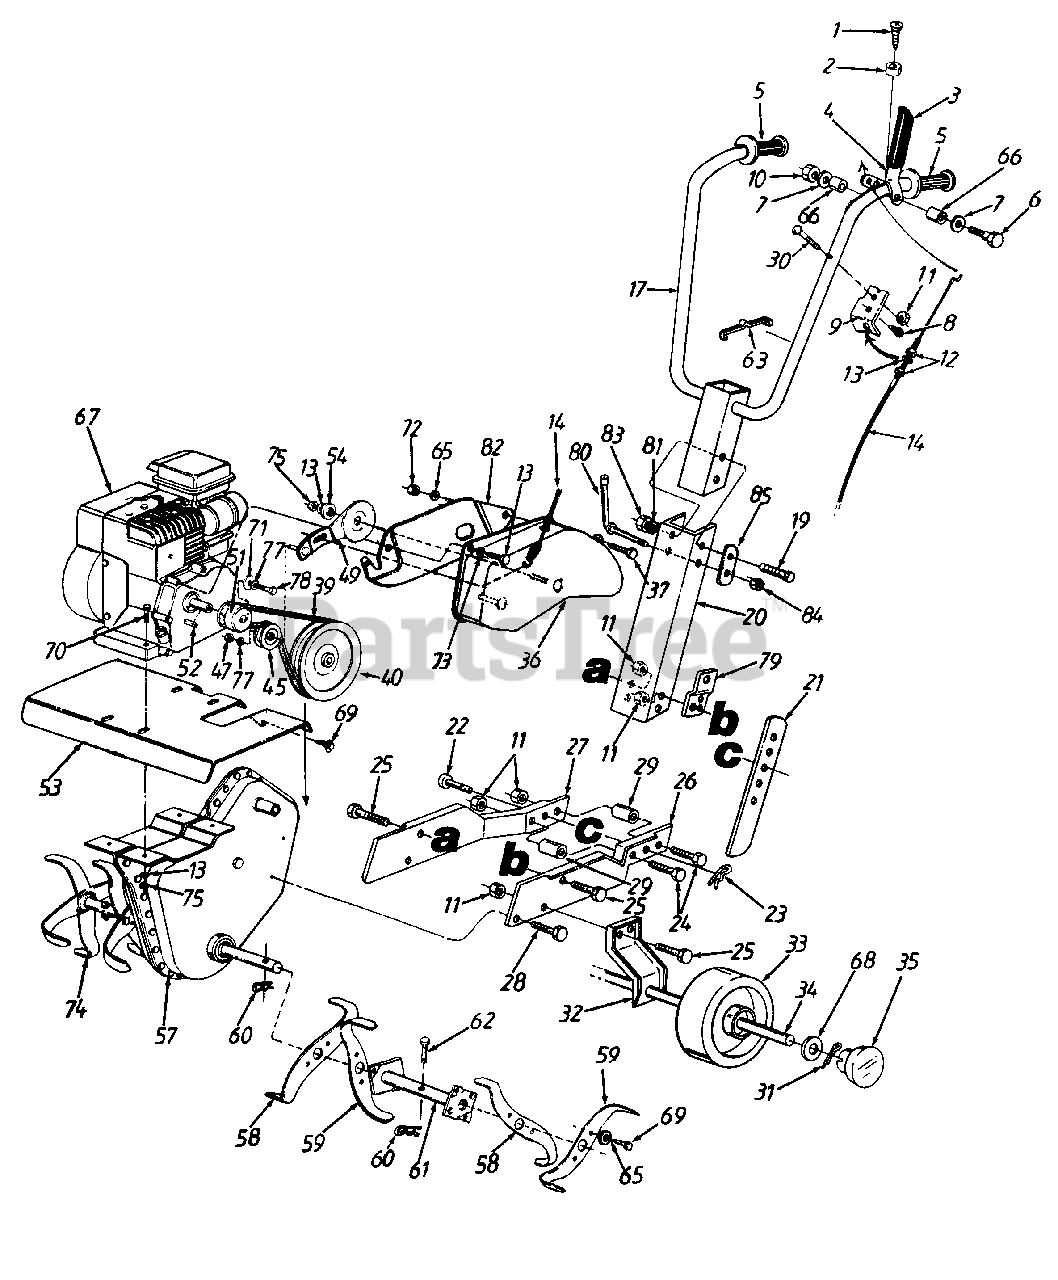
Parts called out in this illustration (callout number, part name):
1	Tap Scr. #10-16 x 1/2" Lg.
2	Rubber Bumper
3	Vinyl Grip
5	Handle Grip
6	Hex Bolt 1/4-20 x 2" Lg.
7	Fl-Wash. 1/4" I.D.
8	Hex Tap Scr. 1/4-20 x 1/2" Lg.
9	Cable Bracket
10	Lock Nut 1/4-20 Thd.
11	Lock Nut 5/16-18 Thd.
12	Hex Jam Nut 5/16-24 Thd.
13	L-Wash. 5/16" I.D.
14	Clutch Control Cable
23	Hairpin Cotter
24	Hex Bolt 5/16-18 x 1" Lg.
25	Hex Bolt 5/16-18 x 5/8" Lg.
29	Spacer
30	Hex Bolt 5/16-18 x 1-1/4" Lg.
31	Cotter Pin
34	Axle-Wheel
35	Hub Cap
39	V-Belt
40	Pulley-Chain Case
45	Flat Idler Pulley
47	Hex Jam L-Nut 3/8-24 Thd.
49	Idler Arm Ass'y.
51	Engine Pulley
52	Square Key 3/16" x .75" Lg.
57	Chain Case Ass'y. Comp.
63	Cable Tie - Plastic
65	L-Wash. 1/4" I.D.
66	Spacer
67	Engine
68	Fl-Wash. 3/8" I.D.
69	Tap Scr. 1/4-20 x 1/2" Lg.
70	Hex Bolt 5/16-18 x 1-1/2" Lg.
71	Fl-Wash. 3/8" 1.D. x 1" O.D.
72	Hex Nut 1/4-20 Thd.
73	Hex Bolt 5/16-24 x .5" Lg.
77	L-Wash. 3/8" I.D.
78	Hex Bolt 3/8-24 x 1" Lg.
81	Fl-Wash. .385" I.D. x .87" O.D.
84	Hex Flange L-Nut 3/8-24 Thd.
85	Retainer Bracket
